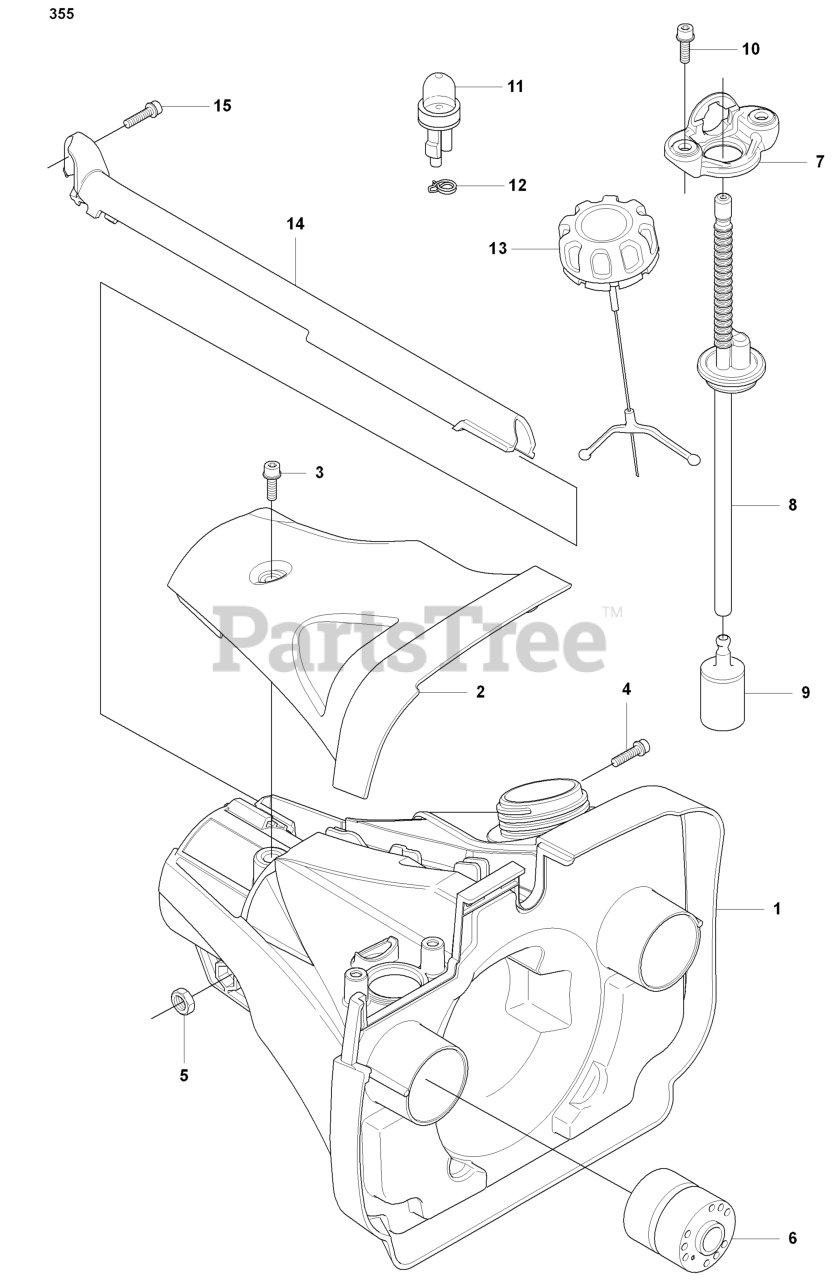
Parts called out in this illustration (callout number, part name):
2	COVER
3	SCREW IHSCFM
6	ANTIVIBE ELEMENT
9	RP FUEL FILTER
11	AIR PURGE BUBBLE
12	HOSE CLAMP
13	TANK CAP
14	WIRING PROTECTION
15	SCREW IHSCFM
